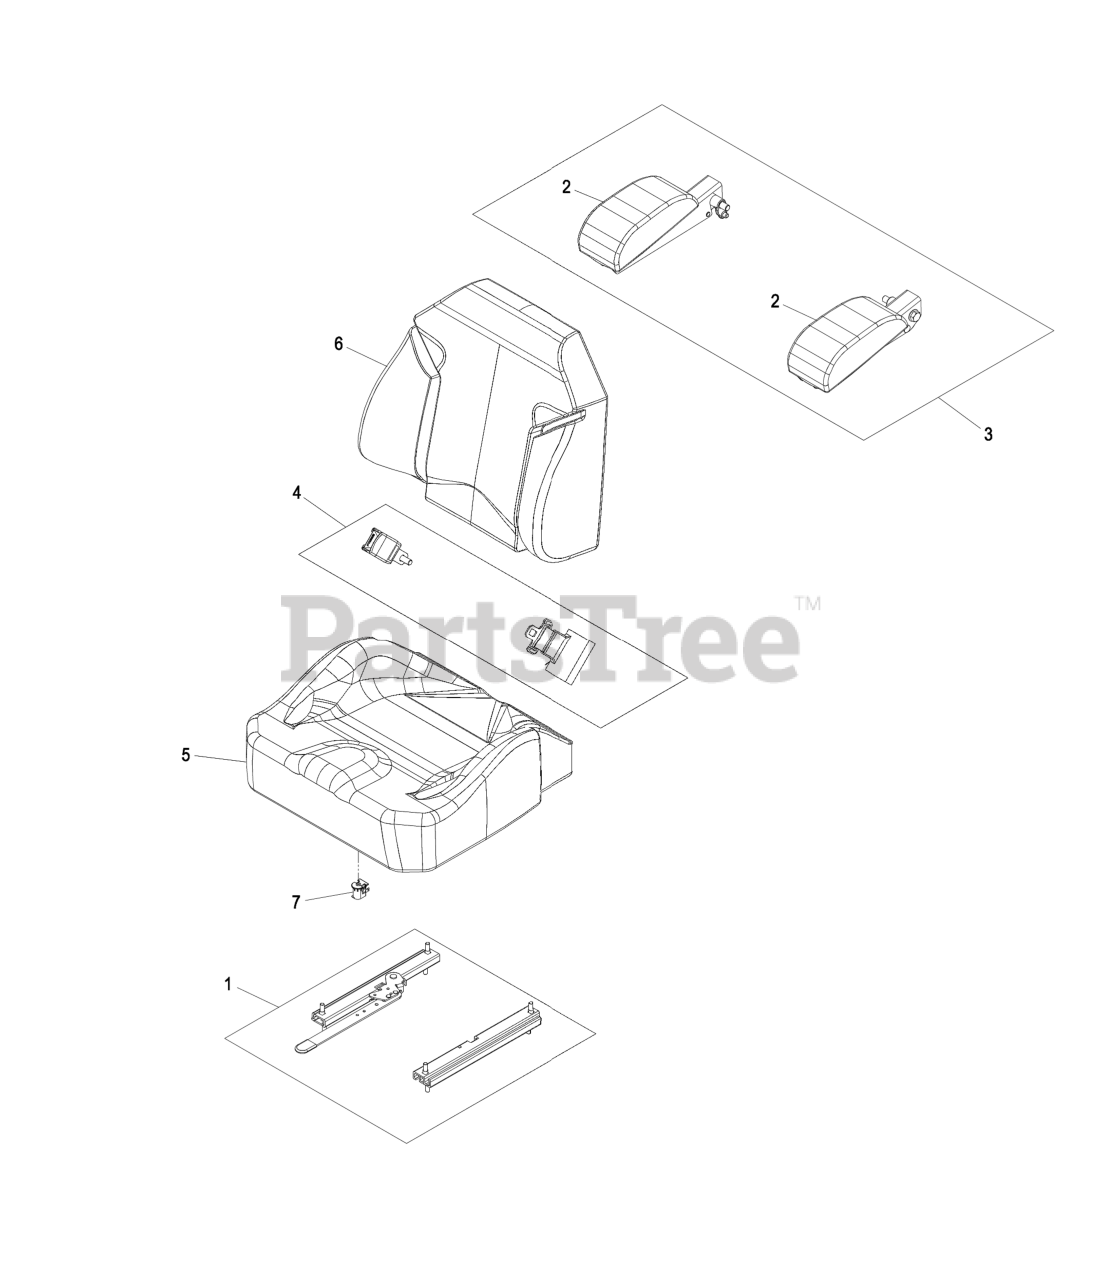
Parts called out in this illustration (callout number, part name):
1	SEAT TRACK SET
2	SET,ARM REST PADS
3	KIT,ARM REST SET
4	SEAT BELT KIT (SHORT)
5	COVER,CUSHION
6	COVER,BACK
7	SWITCH-BAIL
